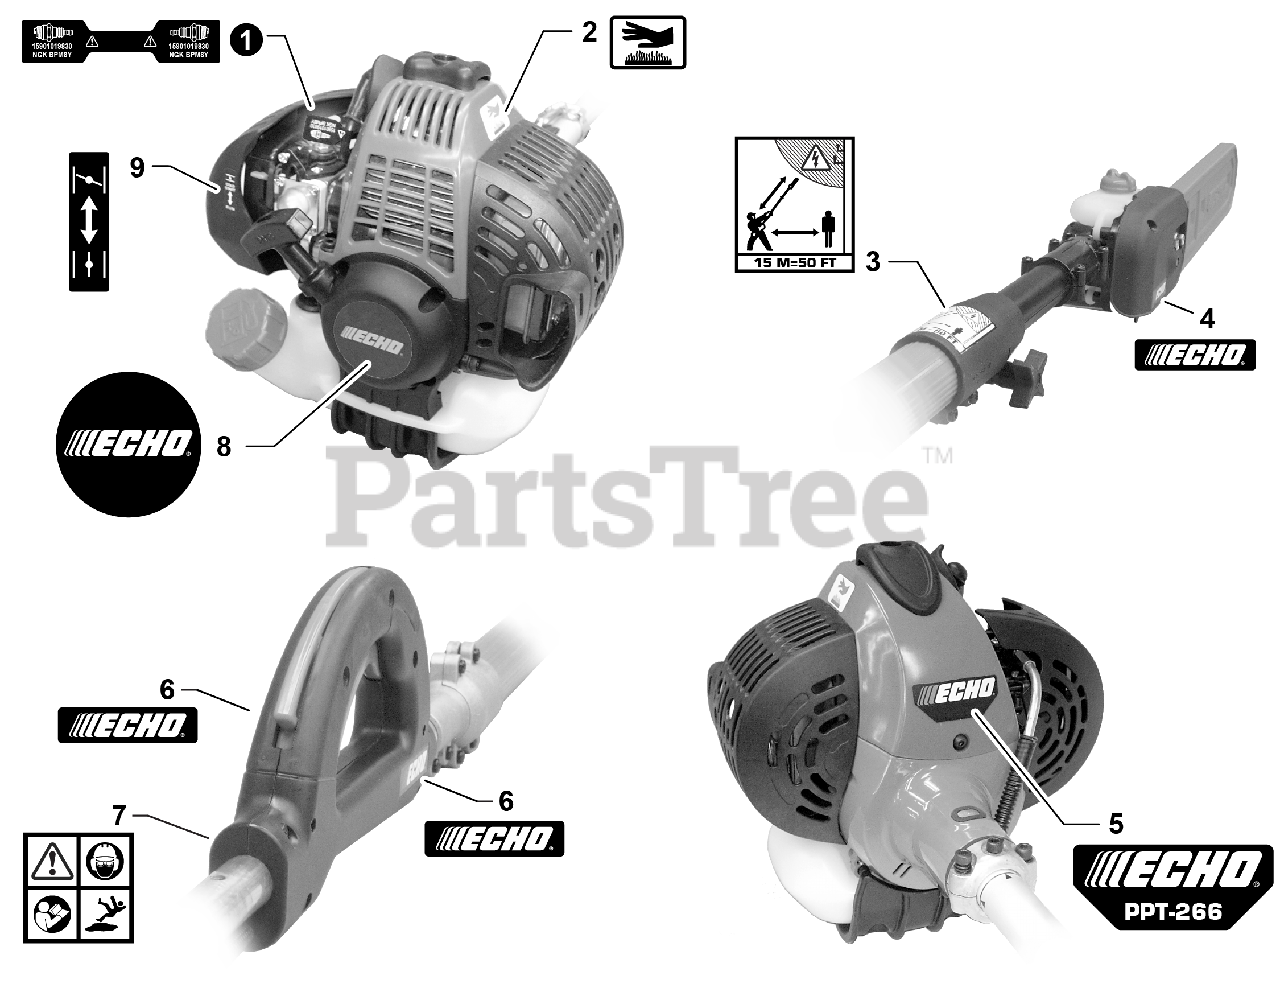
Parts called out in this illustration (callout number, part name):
1	LABEL - SPARK PLUG - BPM8Y
2	LABEL - CAUTION - HOT
3	LABEL - CAUTION
4	LABEL - ECHO
5	LABEL - MODEL PPT-266
6	LABEL - ECHO
7	LABEL - CAUTION
8	LABEL - STARTER - ECHO
9	LABEL - CHOKE
